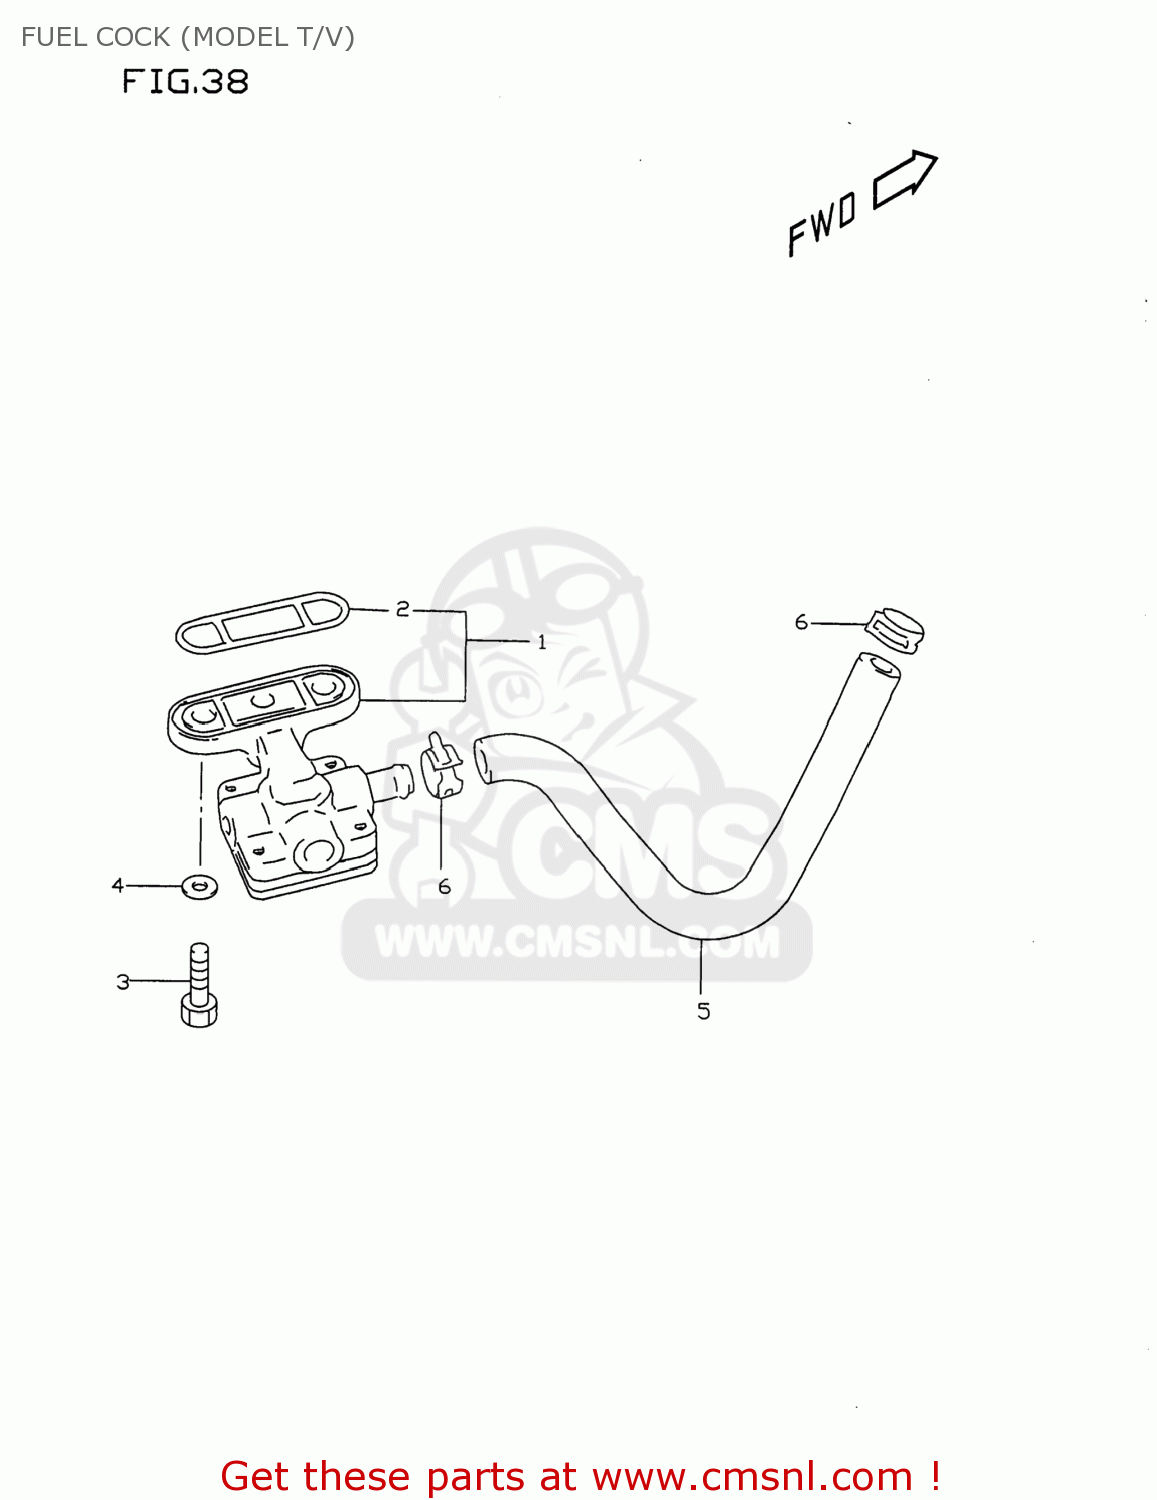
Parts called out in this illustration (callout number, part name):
1	COCK ASSEMBLY,FUEL
2	O RING,JOINT
3	BOLT(6X20)
4	GASKET(6.4X11.5X0.8) (NAS)
5	HOSE(7X12X600)
6	CLIP
